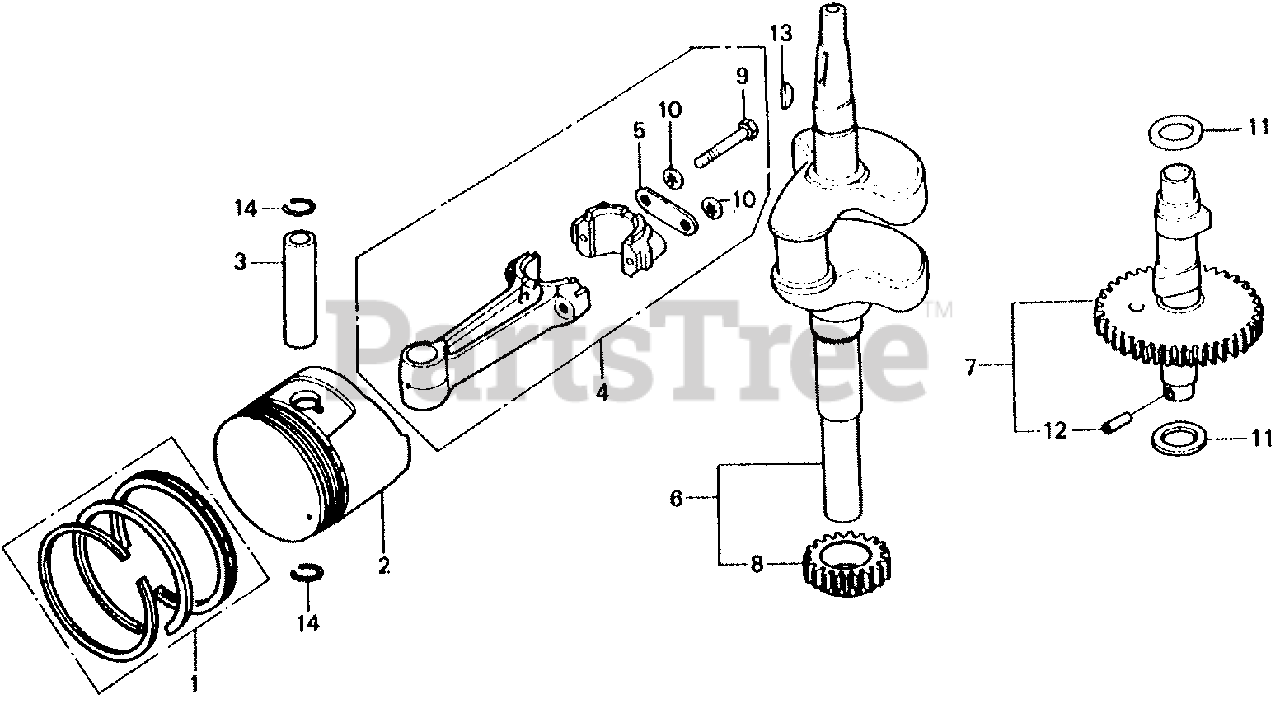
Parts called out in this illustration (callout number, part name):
1	RING SET, PISTON (STD)
1	RING SET, PISTON (OS 0.25) (Honda Code 0635052). (OS)
1	RING SET, PISTON (OS 0.50) (Honda Code 0635060). (OS)
1	RING SET, PISTON (0.75) (OS)
2	PISTON (STD)
2	PISTON (OS 0.25) (OS)
2	PISTON (OS 0.50) (OS)
2	PISTON (0.75) (OS)
3	PIN, PISTON
4	ROD ASSY., CONNECTING
4	ROD ASSY., CONNECTING (Honda Code 0871566). (US 0.25)
5	WASHER, CONNECTING ROD
6	CRANKSHAFT
7	CAMSHAFT ASSY.
8	GEAR, TIMING
9	BOLT, CONNECTING ROD (7MM)
10	WASHER, LOCK (7MM)
11	WASHER, THRUST (18MM)
12	PIN, SPRING (2.5X16)
13	KEY, SPECIAL WOODRUFF (25X18)
14	CLIP, PISTON PIN (15MM)
